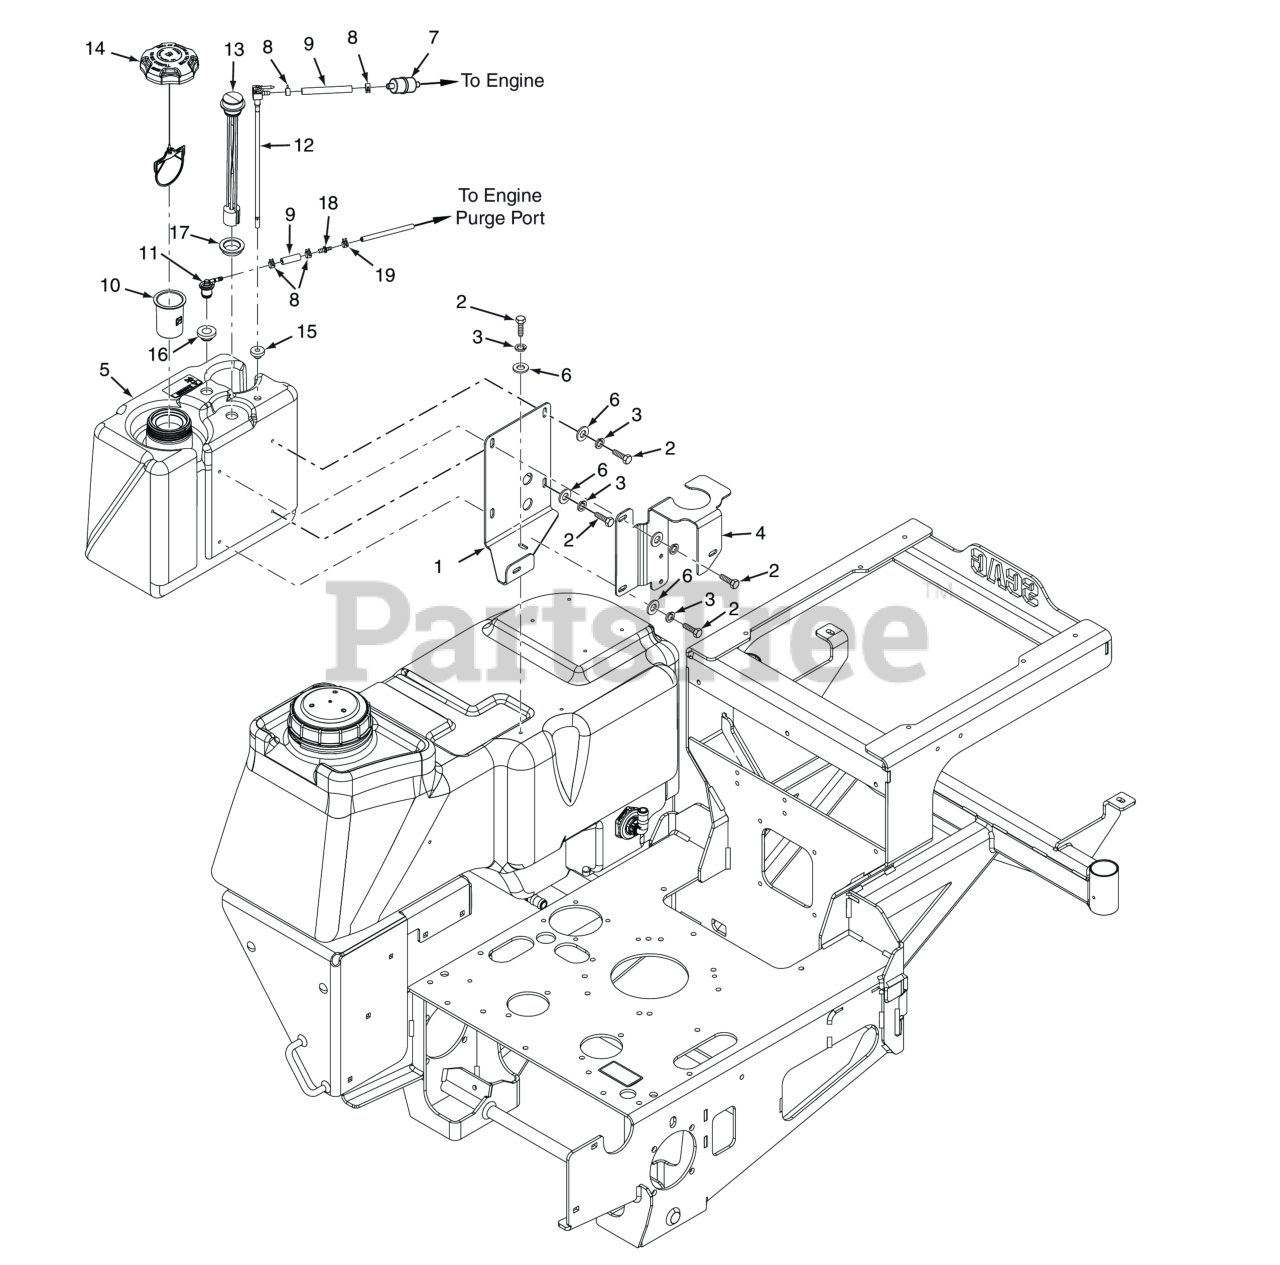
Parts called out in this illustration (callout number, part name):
1	Mounting Bracket, Fuel Tank
2	Bolt, Hex 5/16 - 18 x .75 - Stainless Steel
3	Lockwasher, 5/16 (.317 x .586 x .078) Helical Spring
4	Mounting Bracket, Oil Reservoir
5	Fuel Tank Assembly (incl. #2, 3, 5, 6, 17, 18)
6	Washer, Flat 5/16 -.375 x .875 x .0547/.104 - Stainless Steel
7	Fuel Filter
8	Clamp, Fuel Hose 1/4" Hose I.D.
9	Hose, 1/4" Vapor Recovery (order by inch)
10	TUBE, FUEL INLET - 3.00
11	Remote Vent, No Valve
12	Valve, Fuel Shutoff w/Screen
13	Fuel Gauge Assembly
14	Fuel Cap w/ Tether (E.P.A.)
15	Bushing, 0.56" Dia. Viton
16	Grommet, Viton,
17	Grommet, Fuel Gauge
18	Mender, 1/4 x 3/16 w/0.02 Hole
19	Clamp, Vapor Recovery Hose 3/16"
